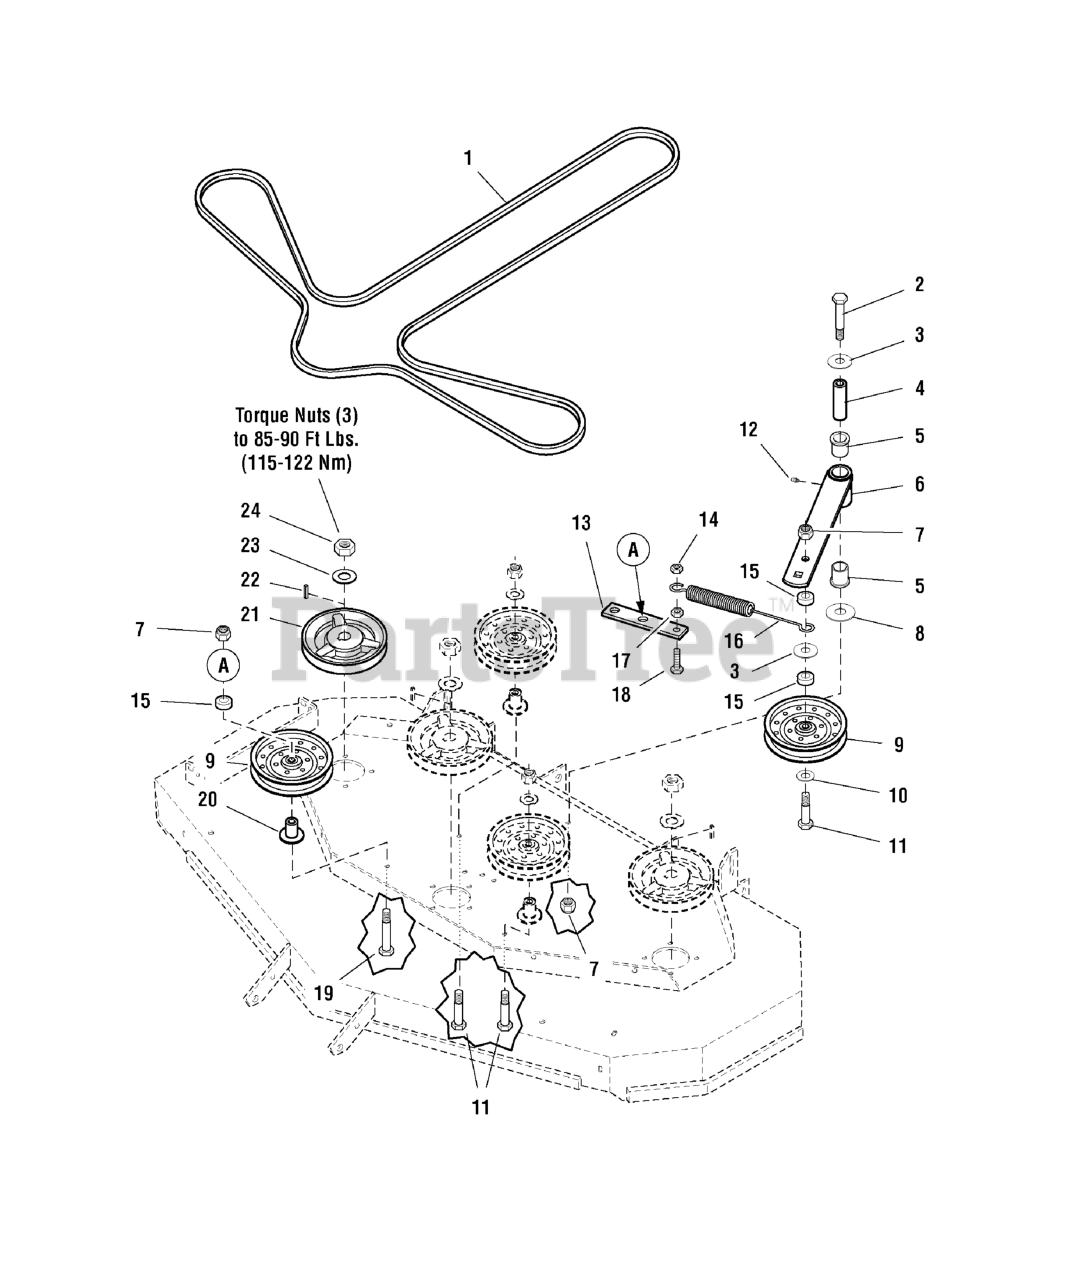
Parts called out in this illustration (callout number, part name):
1	BELT, 5V, 175.90EL, LG ARAMID, WRPD, RC
2	BOLT, 1/2-13 x 4-1/2
3	WASHER, 1/2" USS
4	SPACER, .52 x 1.00 x 3.50
5	BUSHING, FLANGE
6	IDLER ARM
7	NUT, 1/2-13 HEX NYLON LOCK
8	WASHER, 5/8" SAE
10	WASHER, 1/2 SAE
11	BOLT, 1/2-13 X 3" GD5 CZ
12	GREASE FITTING
13	MOUNT, Idler Spring
14	NUT, 3/8-16 Hex Top Lock
15	SPACER, .52 x 1.00 x .44
16	SPRING, Extension, Swivel End
17	NUT, 3/8-16 Hex
18	BOLT, 3/8-16 X 1-1/4" GD5 CZ
19	BOLT, 1/2-13 X 3-1/2, HEX HD, GD5, CZ (SV)
20	IDLER MOUNT
21	SPINDLE PULLEY
22	KEY, 1/4 SQ. X 1-1/4
23	WASHER, 3/4 BELLEVILLE
24	NUT, 3/4-16 Hex
